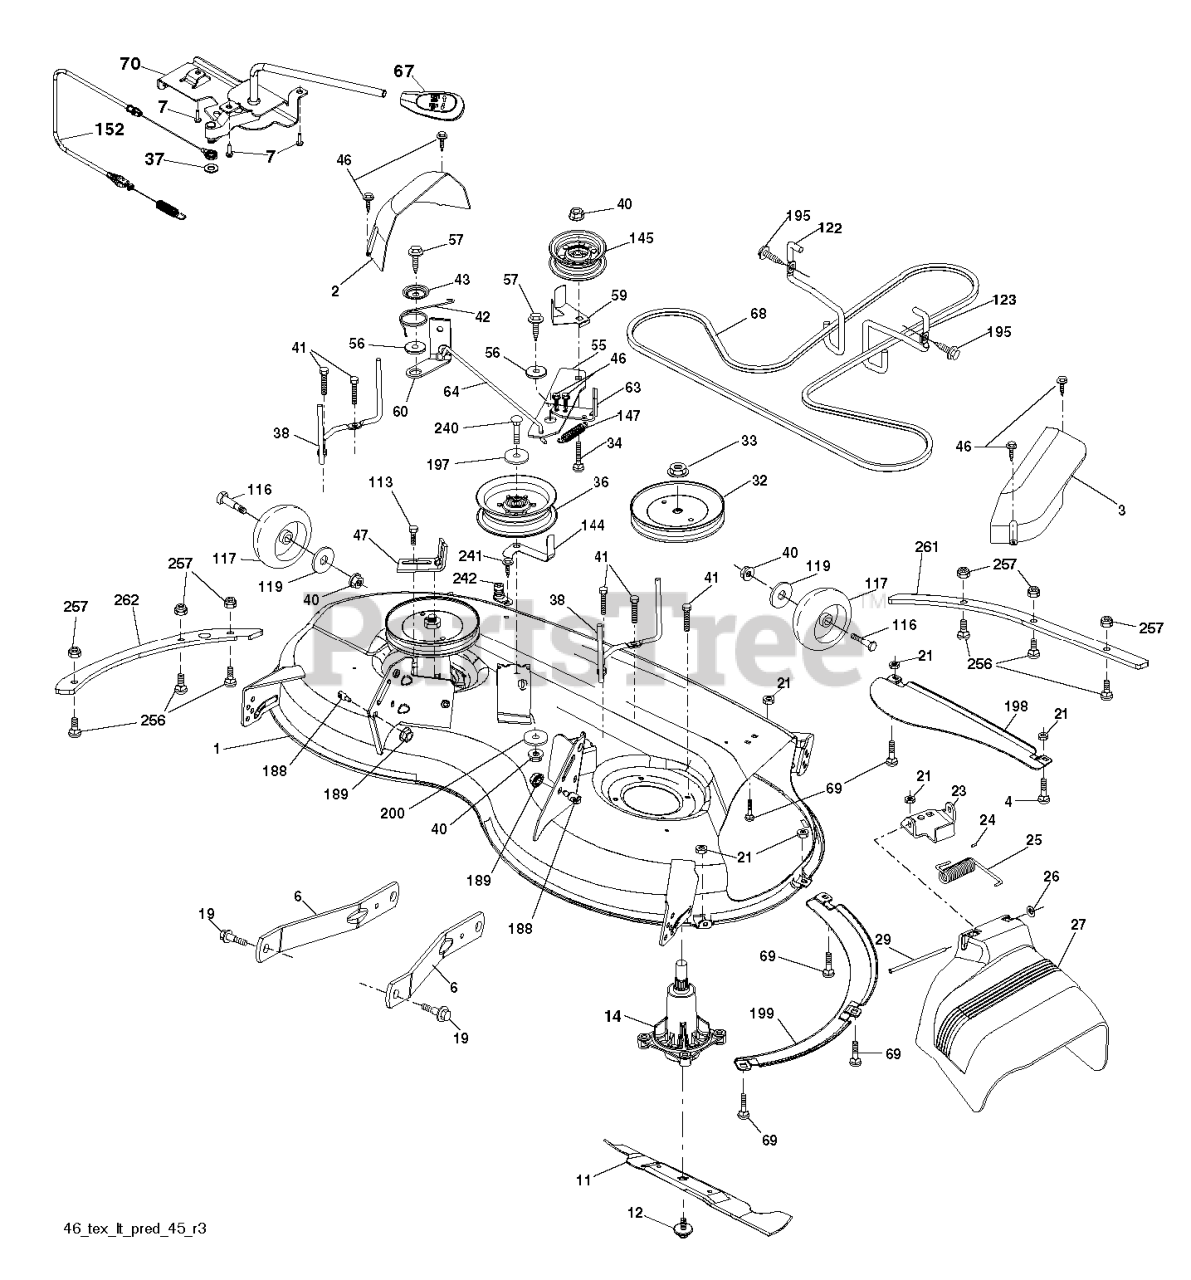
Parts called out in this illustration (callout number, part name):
2	VALVE STEM LT
3	TIRE HEAVY DUTY
4	TUBE.5.3/4.5/6
5	RIM ASM 6" FRONT SILVER
6	FITTING LT
7	BEARING T
8	RIM ASM 8" REAR SILVER
9	TIRE
10	TUBE
11	CAP, AXLE BLK
